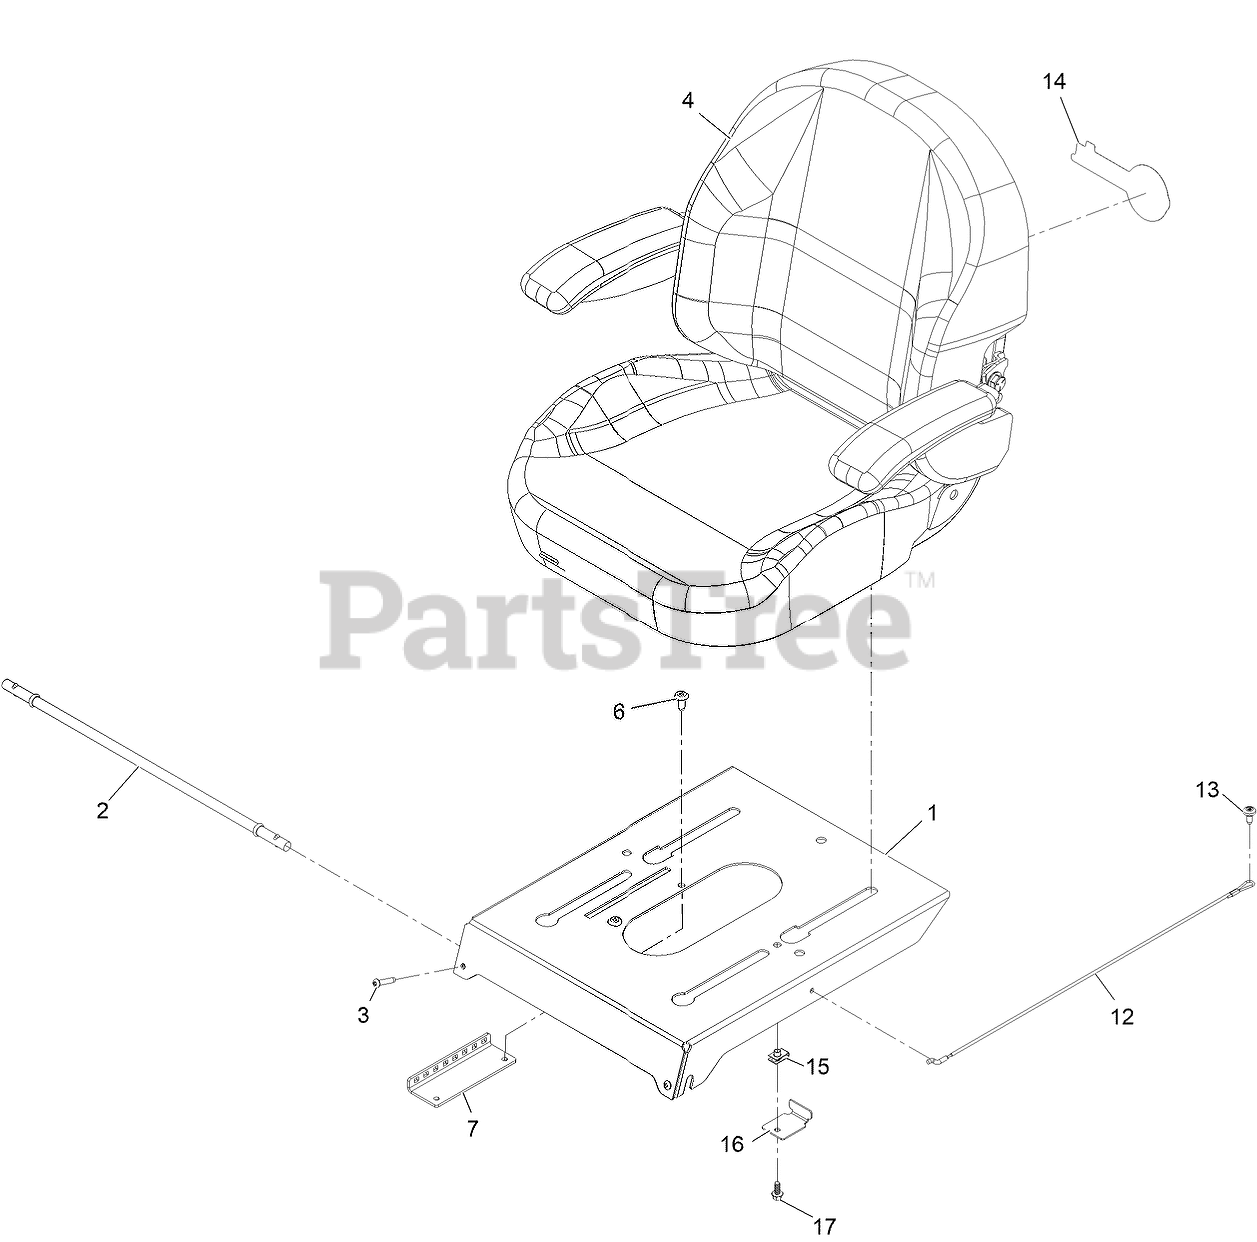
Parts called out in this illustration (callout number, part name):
2	ROD-PIVOT
3	SCREW-TTH, THREAD ROLLING
4	ASM-Seat Exmark
7	BRACKET-LATCH, SEAT
12	CABLE-LANYARD
13	SCREW-SHOULDER
14	DECAL-EXMARK LOGO
16	Bracket-Stop, Seat
17	SCREW-HHF
